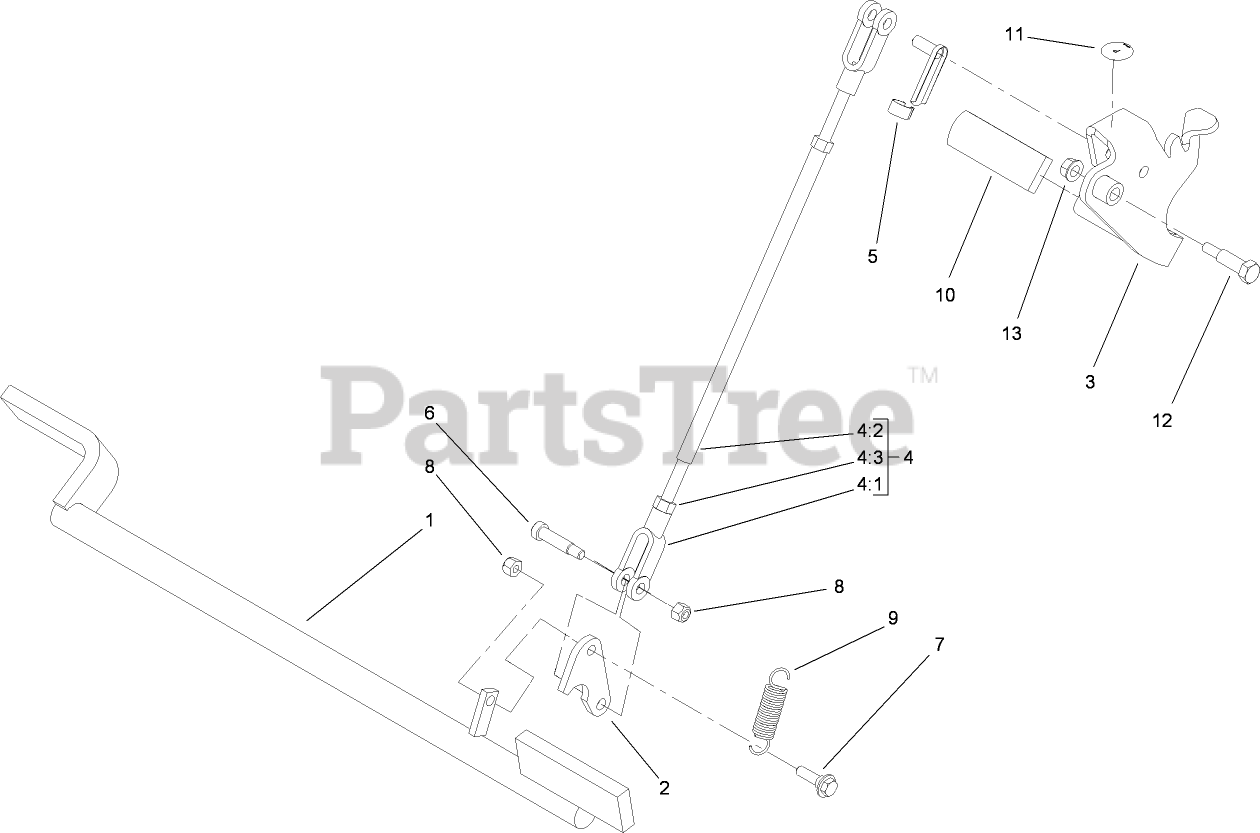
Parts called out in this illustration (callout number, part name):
1	BAR-BRAKE
2	LINK-MOUNTING
3	BRAKE HANDLE ASM
4	BRAKE ROD ASM
4:1	YOKE-LINKAGE, BRAKE
4:2	LINKAGE-HANDLE, BRAKE
4:3	NUT-HEX
5	Pin-Spring, Clevis
6	BOLT-SHOULDER
7	SCREW-SHOULDER
8	NUT-LOCK, NI
9	SPRING-IDLER
10	GRIP-HANDLE
11	DECAL-PARKING BRAKE
12	SCREW-SHOULDER, HH
13	NUT-HF
